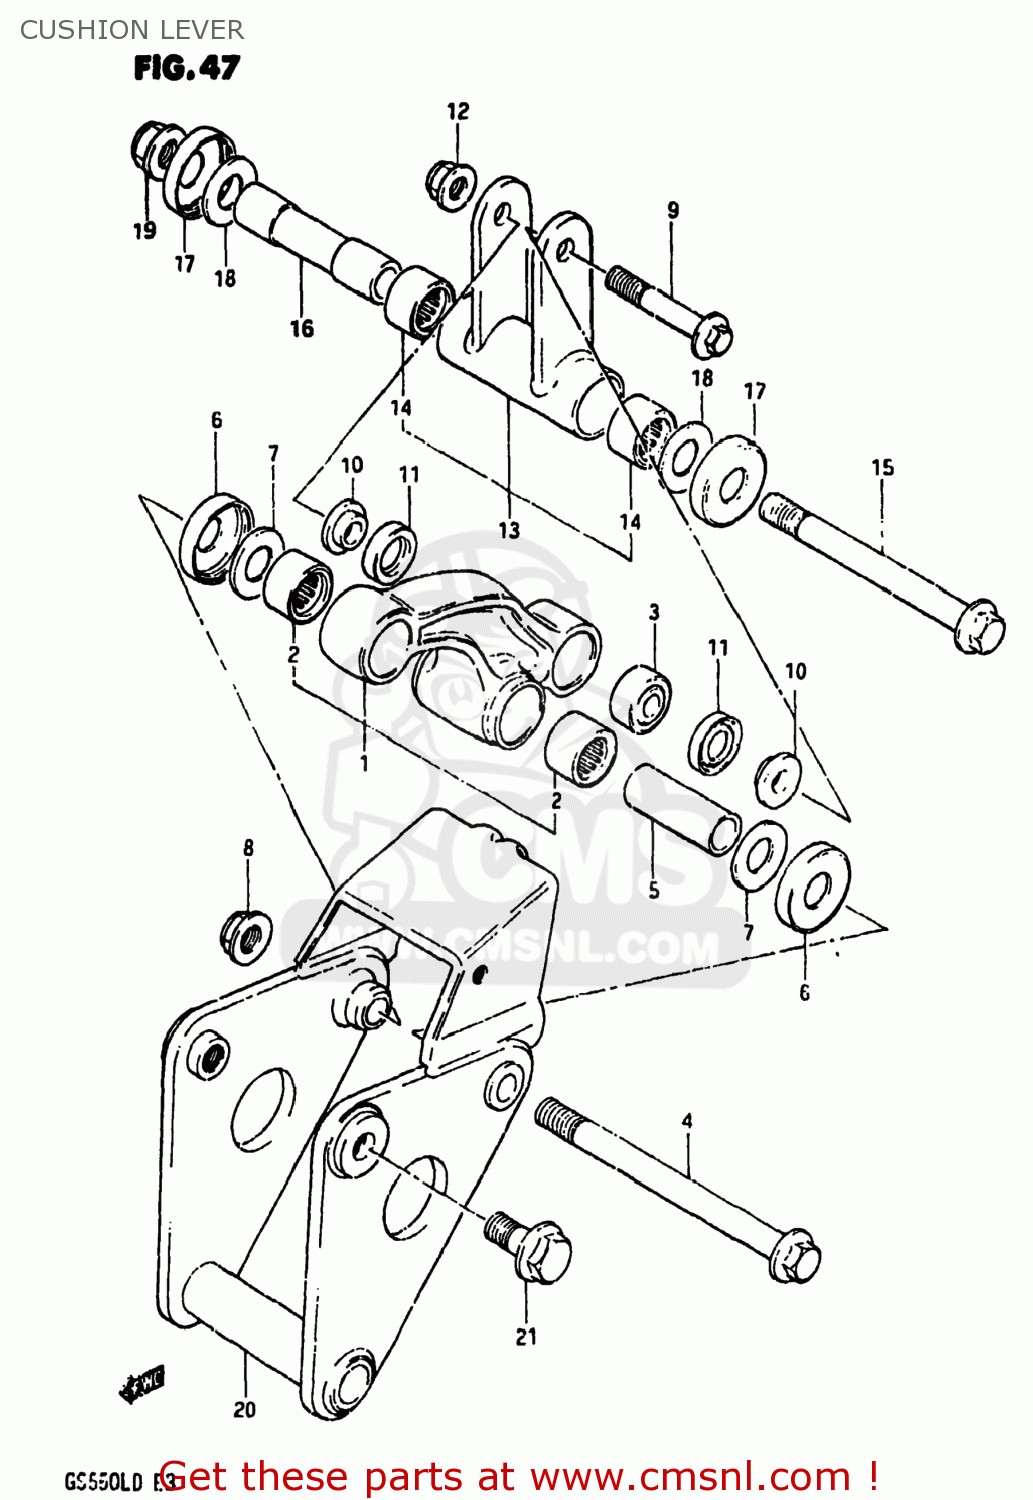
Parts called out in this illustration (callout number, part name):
1	LEVER ASSEMBLY,REAR CUSHION
2	ROLLER BEARING (17X24X2
3	BEARING(10X24X15)
4	SHAFT,REAR CUSHION LEVER
5	SPACER,REAR CUSHION LEVER
6	COVER,RR SWGARM DUST SEAL
7	WASHER
8	NUT 12MM
9	BOLT(10X52)
10	SPACER
11	DUST SEAL,RR CUSHION LEVER RR
12	NUT
13	ROD SET,REAR CUSHION LEVER
14	ROLLER BEARING (17X24X2
15	BOLT,REAR CUSHION ROD
16	SPACER,REAR CUSHION ROD
17	COVER,RR SWGARM DUST SEAL
18	WASHER
19	NUT 12MM
20	HOLDER
21	BOLT(12X23)
